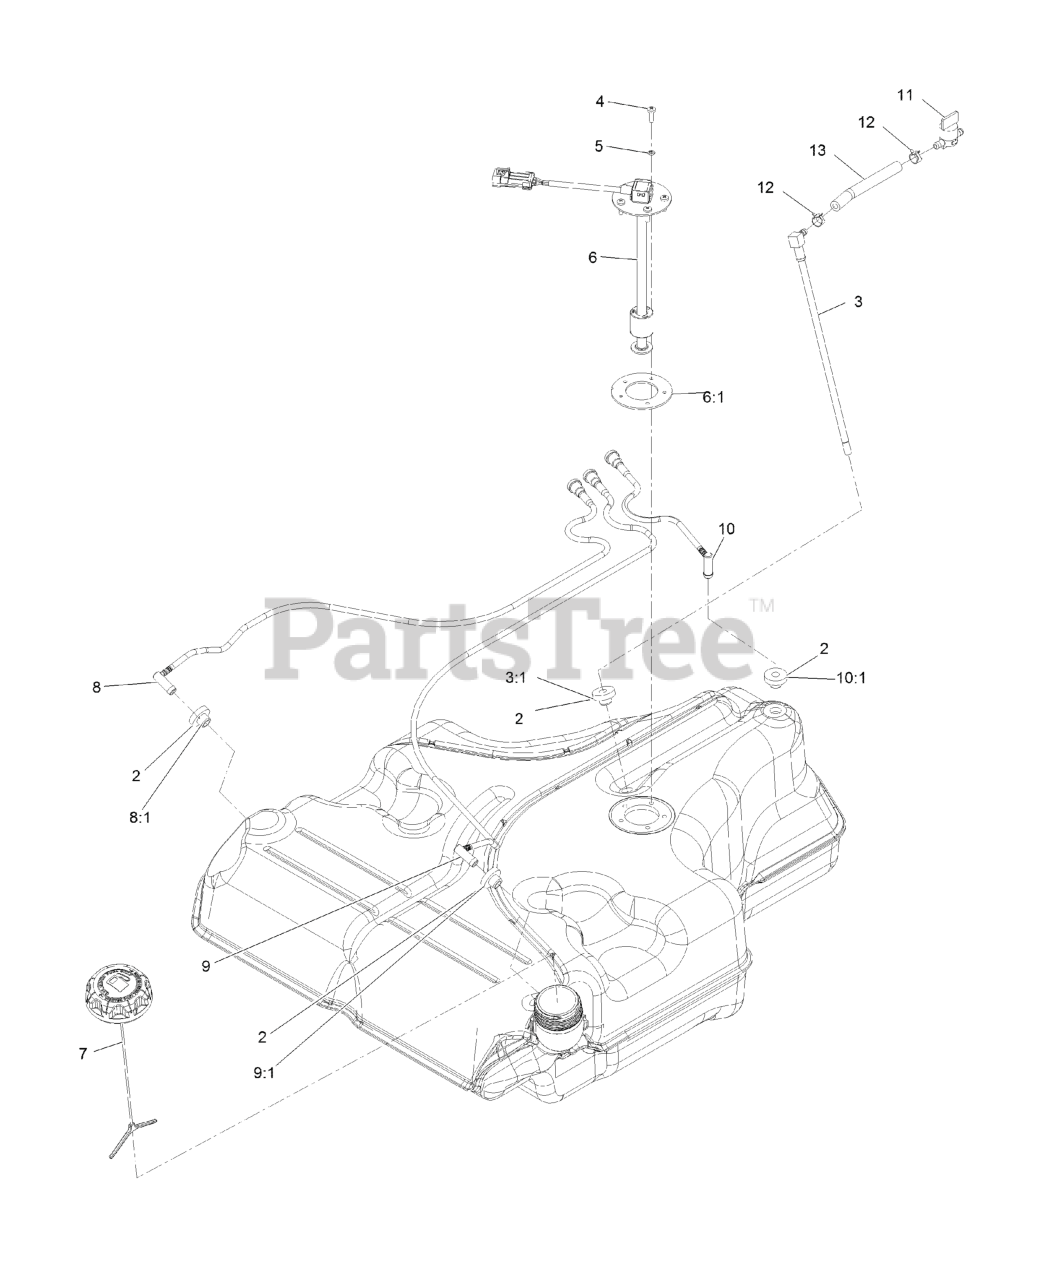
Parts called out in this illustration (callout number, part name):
2	BUSHING
3	FUEL LINE KIT (WITH GROMMET)
3:1	BUSHING
4	SCREW-PPH
5	WASHER-LOCK
6	FLOAT-SENDER, FUEL
6:1	Gasket-Sender
7	CAP-FUEL, RATCHETING
8	RH VENT LINE KIT (WITH GROMMET)
8:1	BUSHING
9	LH VENT LINE KIT (WITH GROMMET)
9:1	BUSHING
10	REAR VENT LINE KIT (WITH GROMMET)
10:1	BUSHING
11	VALVE-FUEL
12	CLAMP-HOSE
13	HOSE-FUEL
